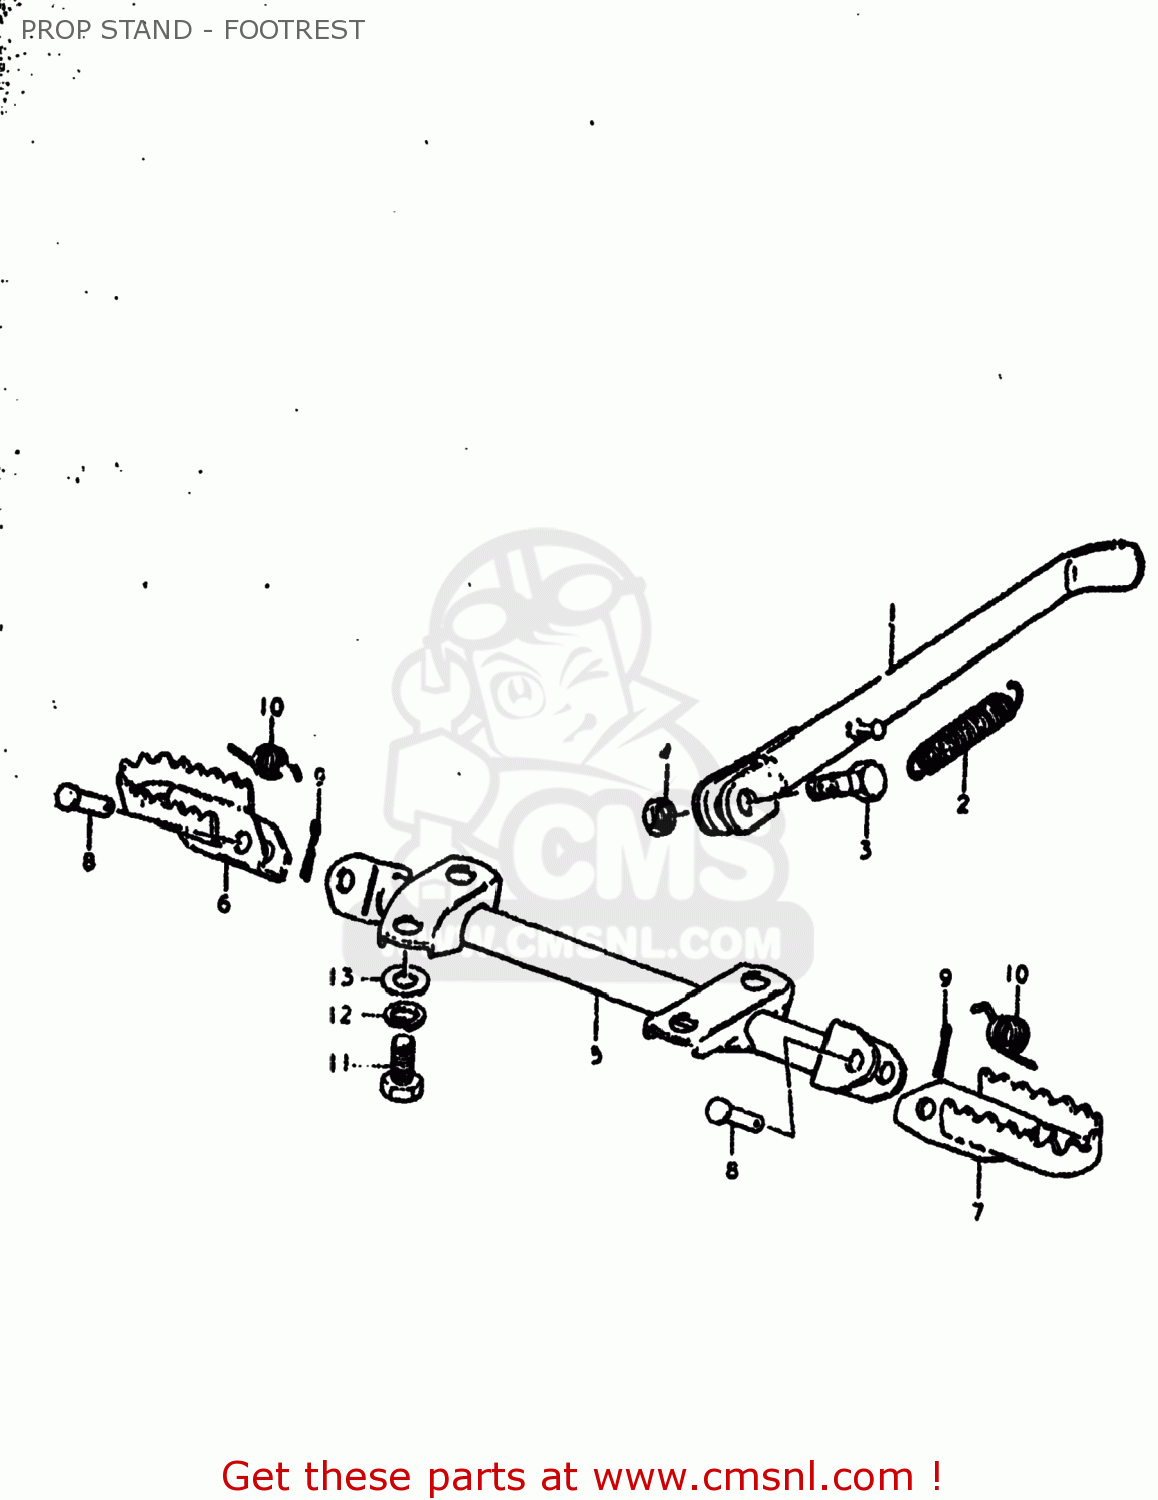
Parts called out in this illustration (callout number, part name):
1	STAND,SIDE
2	SPRING
3	BOLT(10X30)
4	NUT
5	BAR,FR FOOTREST
6	FOOTREST,FR,R
7	FOOTREST,FR,L
8	PIN
9	PIN 20X20
10	SPRING
11	BOLT
12	LOCK WASHER
13	WASHER
